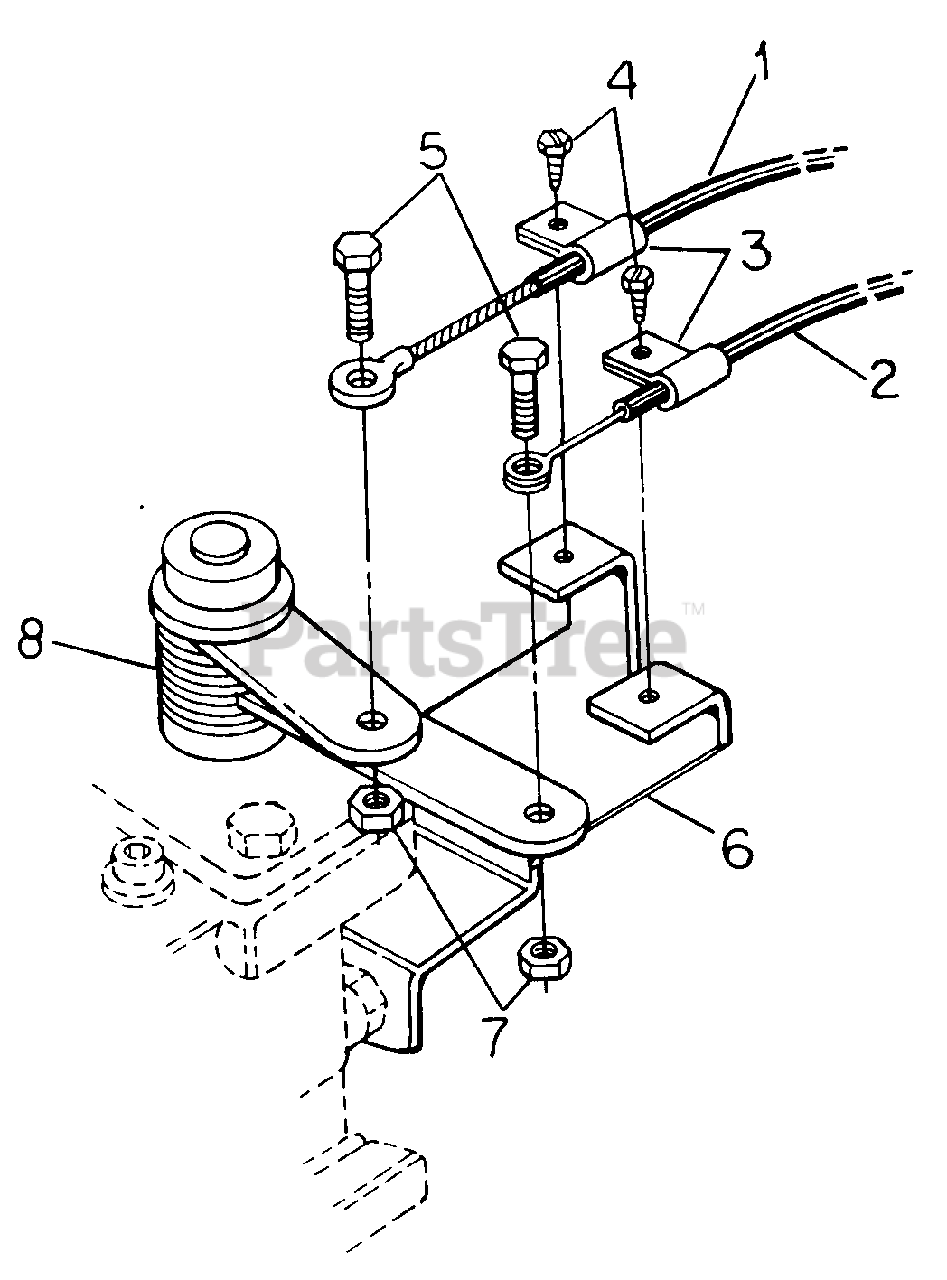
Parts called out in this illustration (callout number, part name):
1	Cable, Shut-Off
2	Cable, Throttle
3	Clamp, Conduit
4	Screw, 10-16 X 5/8 H/Hd Tap
5	Bolt, 5/16 X 1 Type 5
6	Bracket, Control
7	Nut, 5/16 Cad P/T Lock Type 5
8	Speed Control Unit
